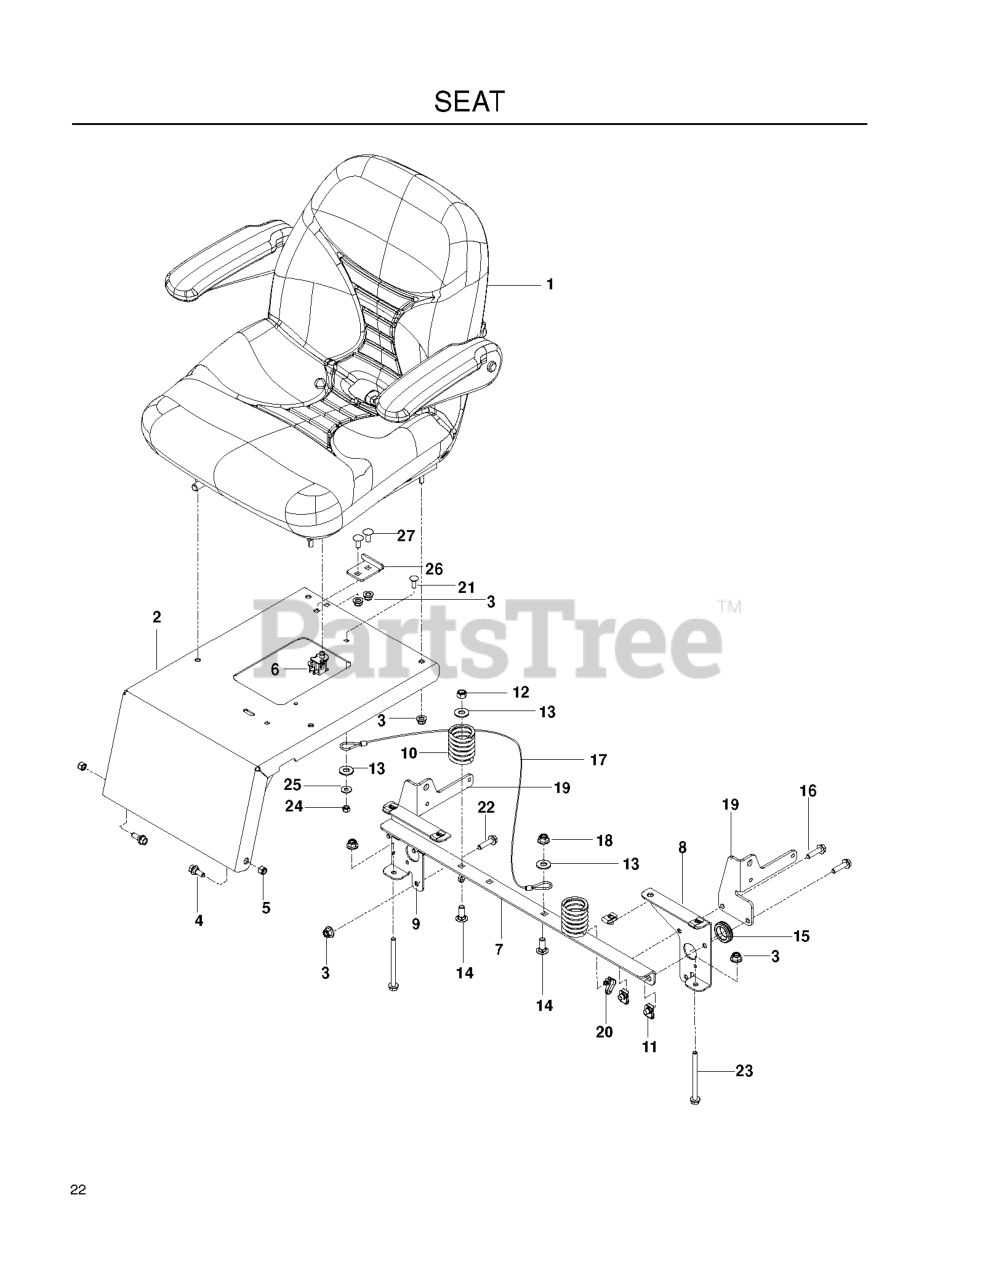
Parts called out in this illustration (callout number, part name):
1	SEAT
2	KIT.SEAT.MOUNT.W/DECAL
3	5/16-18 NYLOC FLANGE NUT
4	SB 5/16-18 HEX HD GD5, BLK ZN
5	NUT 5/16 NYLOC
6	SEAT SWITCH
7	SUPPORT, SEAT
8	SUPPORT, LT, BLK
9	SUPPORT, RT, BLK
10	SPRING, SEAT
11	U-CLIP 5/16-18 NUT RETAINER
12	NUT 3/8-16 NYLOC
13	WASHER 3/8 FLAT
14	RHSNB 3/8C X 1
15	RUBBER GROMMET
16	HHFS 5/16-18 X 1.25 TPBLT GD 5
17	SEAT LANYARD
18	NUT 3/8-16 HEX FLG NYLOC ZD
19	MOUNT, SEAT BELT, BLACK
20	TIE WRAP, 8-3/8", W/CLIP
21	RHSNB 1/4C X 3/4
22	RP BLT 5/16-18 X 1 THRD FORM D
23	HHFS 5/16-18 X 3 3/4
24	NUT.1/4-20.HEX.NYLOC.ZD
25	WASHER 1/4 FLAT
26	STOP, SEAT - BLACK
27	RHSNB 5/16-18 X 3/4
